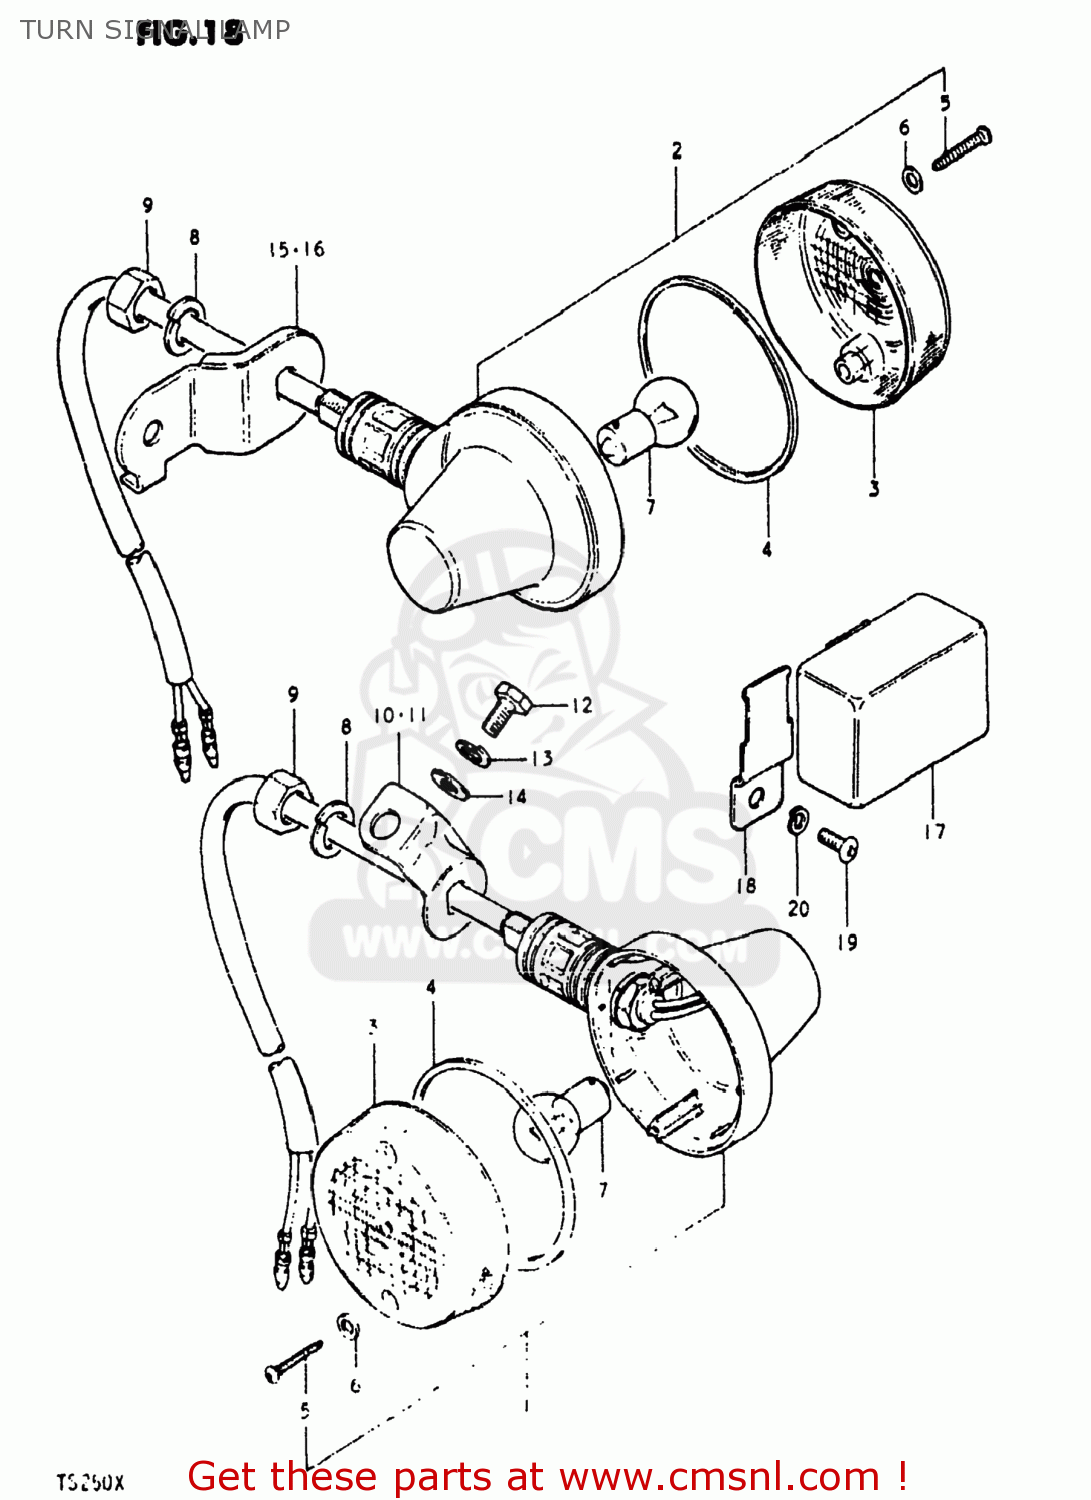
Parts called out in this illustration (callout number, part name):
1	LAMP ASSY,RR TURNSIGNAL
2	LAMP ASSY,RR TURNSIGNAL
3	LENS
4	GASKET (NAS)
5	SCREW TAPP.
6	GASKET (NAS)
7	BULB(6V17W,STANLEY,A4513A)
8	WASHER,LOCK 12
9	NUT
10	BRACKET,TURN SIGNAL LAMP
11	BRACKET,TURN SIGNAL LAMP
12	BOLT
13	LOCK WASHER
14	WASHER
15	BRACKET,REAR TURN SIGNAL
16	BRACKET,REAR TURN SIGNAL
17	RELAY,TURN SIGNAL
18	BRACKET,TURN SIGNAL RELAY
19	SCREW 6X12
20	LOCK WASHER
